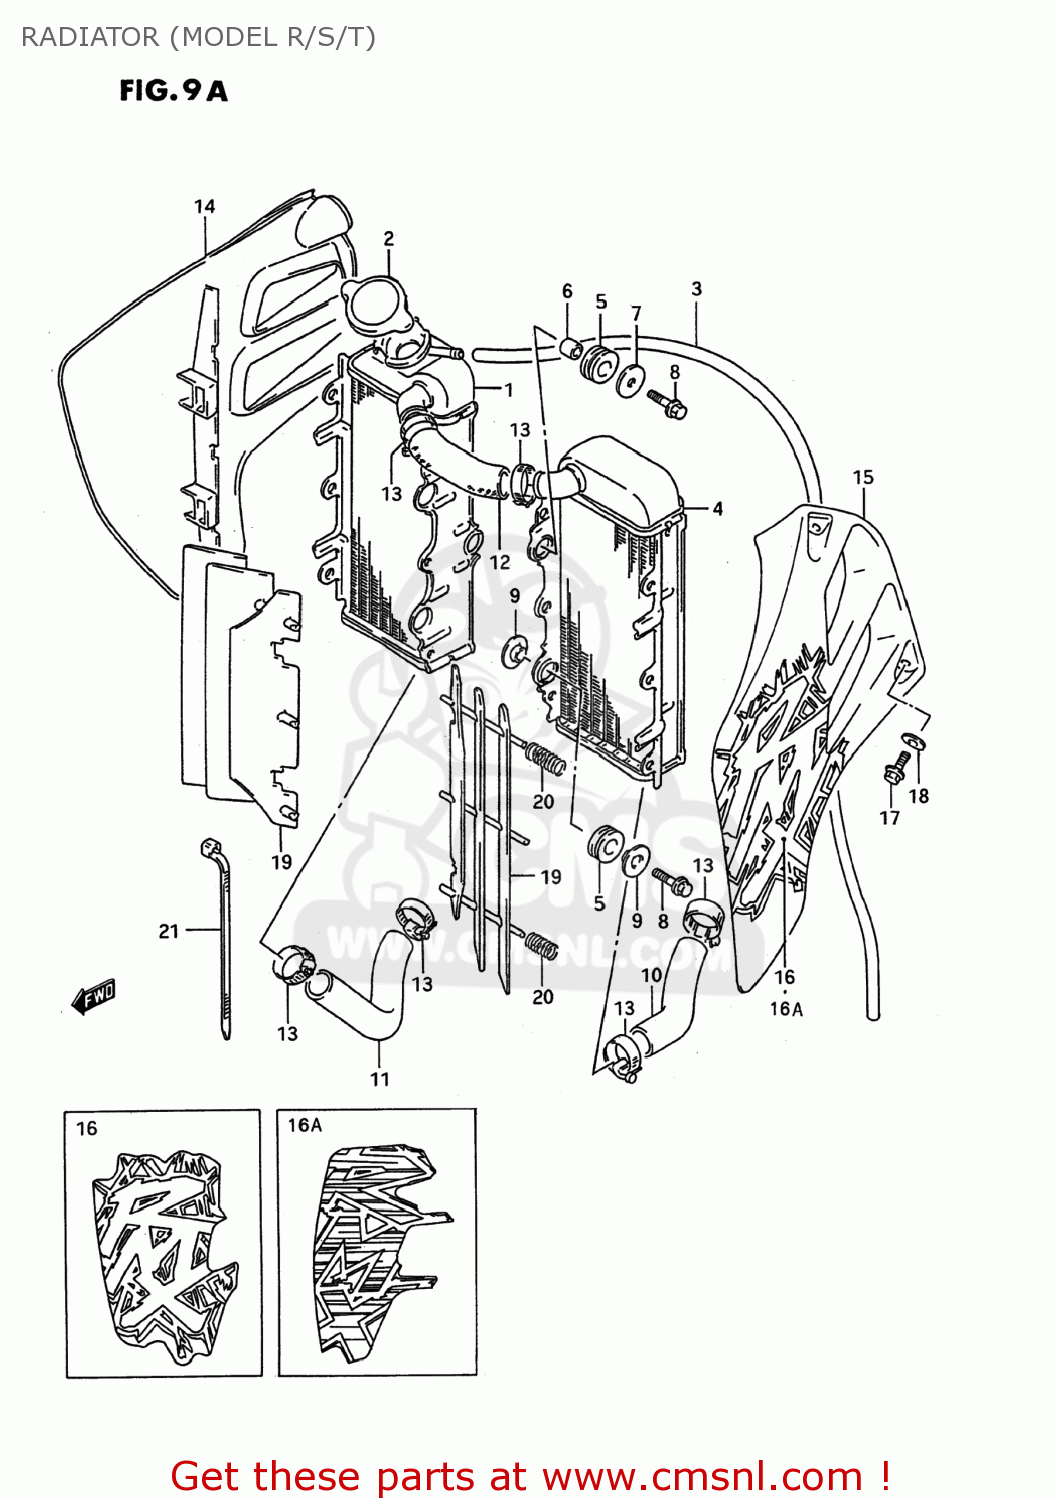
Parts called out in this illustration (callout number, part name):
1	RADIATOR,WATER,R
2	CAP,RADIATOR
3	HOSE(5X8X2000)
4	RADIATOR COMP,WATER,LEFT
5	CUSHION,RADIATOR LWR
6	SPACER(6.5X10.5X12)
7	WASHER (6.5X24X1.2)
8	SCREW
9	WASHER,RDTR SPRT
10	HOSE,RADIATOR INLET
11	HOSE,RADIATOR OUTLET
12	HOSE,RADIATOR JOINT NO.1
13	CLAMP
14	COVER,RADIATOR,R
15	COVER,RADIATOR,L
16	EMBLEM,RADIATOR COVER
16A	TAPE,RADIATOR COVER,L
17	BOLT
18	WASHER
19	LOUVER,RADIATOR
20	SPRING
21	CLAMP L:165
